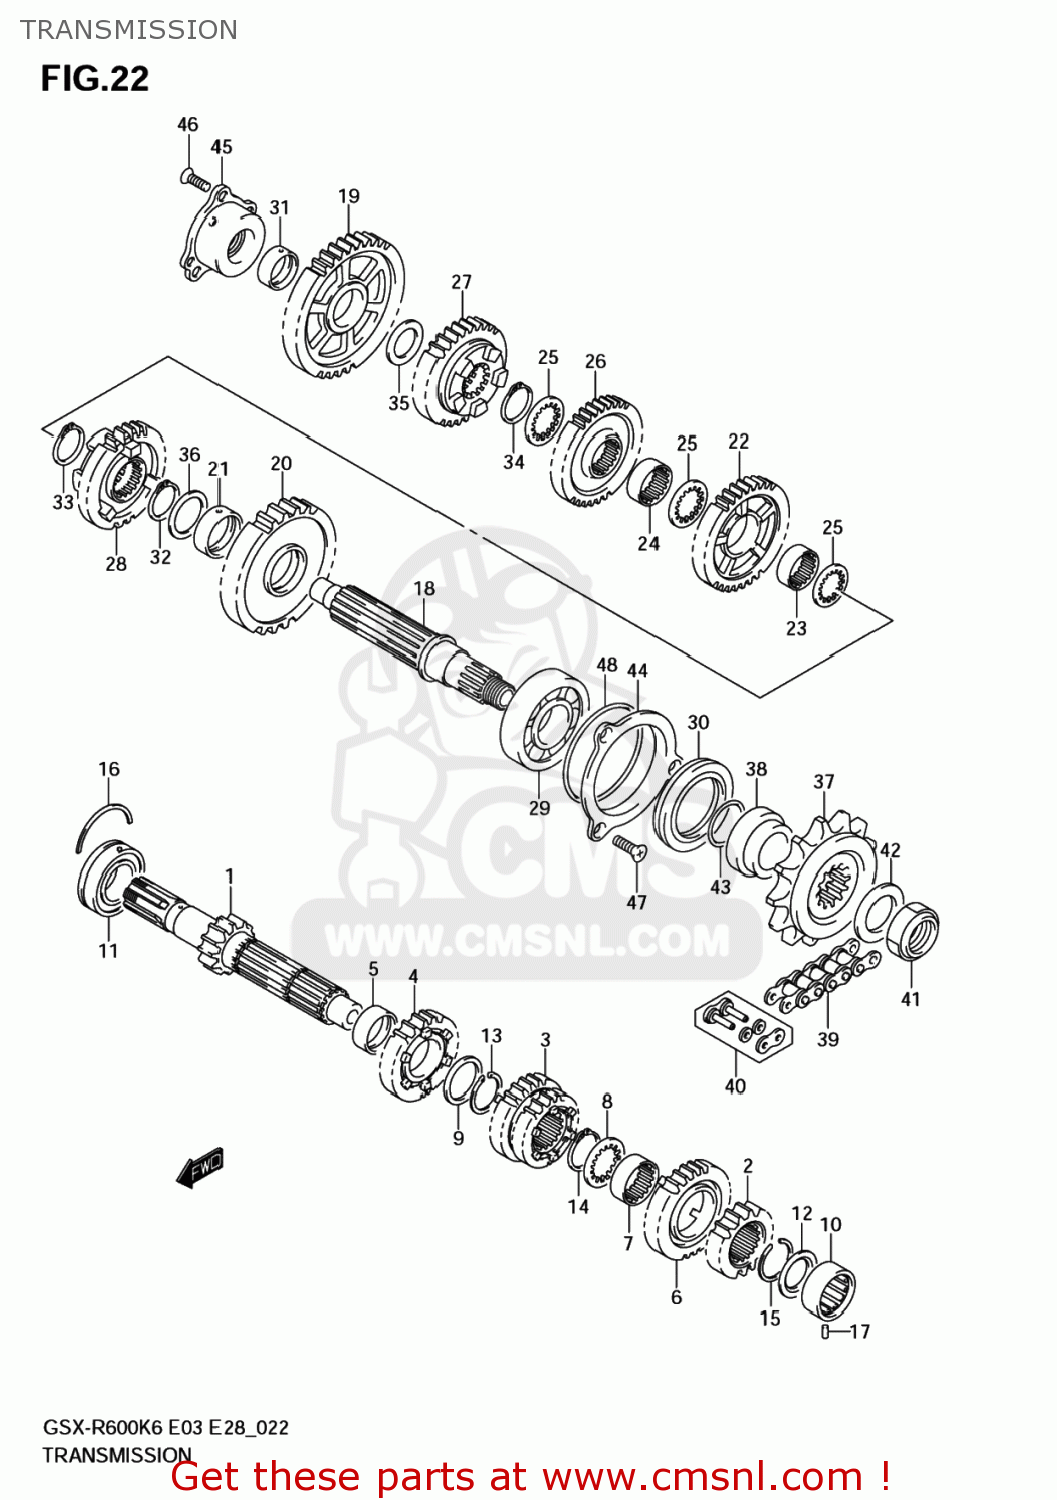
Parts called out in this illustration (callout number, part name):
1	SHAFT,COUNTER
2	GEAR,2ND DRIVE
3	GEAR,3RD & 4TH DRIVE
4	GEAR,5TH DRIVE
5	BUSH,5TH DRIVE GEAR
6	GEAR,6TH DRIVE
7	BUSH,6TH DRIVE GEAR
8	WASHER,LOCK
9	WASHER(27X36X1)
10	BEARING(20X34X13.5)
11	BEARING(25X62X17)
12	SEAL,OIL(20X31.2X2.7)
13	CIRCLIP
14	CIRCLIP
15	CIRCLIP
16	C RING
17	PIN(6X10)
18	SHAFT,DRIVE
19	GEAR,1ST DRIVEN
20	GEAR,2ND DRIVE
21	BUSH,2ND DRIVEN GEAR
22	GEAR,3RD DRIVE
23	BUSH
24	BUSH
25	WASHER,3RD & 4TH DRIVEN
26	GEAR,4TH DRIVEN
27	GEAR,5TH DRIVE
28	GEAR,6TH DRIVEN
29	BEARING(28X68X18)
30	SEAL,OIL(42X62X7)
31	BUSH(22X26X9)
32	CIRCLIP
33	CIRCLIP
34	CIRCLIP
35	SHIM(22X34X1)
36	WASHER(27X36X1)
37	SPROCKET,ENGINE(16T)
38	SPACER,ENGINE SPROCKET
39	CHAIN ASSY,DRI
40	JOINT SET
41	NUT
42	WASHER(25X41X3)
43	O RING(D:2.4,ID:23.7)
44	RETAINER,DRIVE
45	HOUSING,DRIVE SHAFT SET
46	SCREW. DRIVE SH
47	SCREW. DRIVE SH
48	O RING(D:1.9,ID:67.5)
